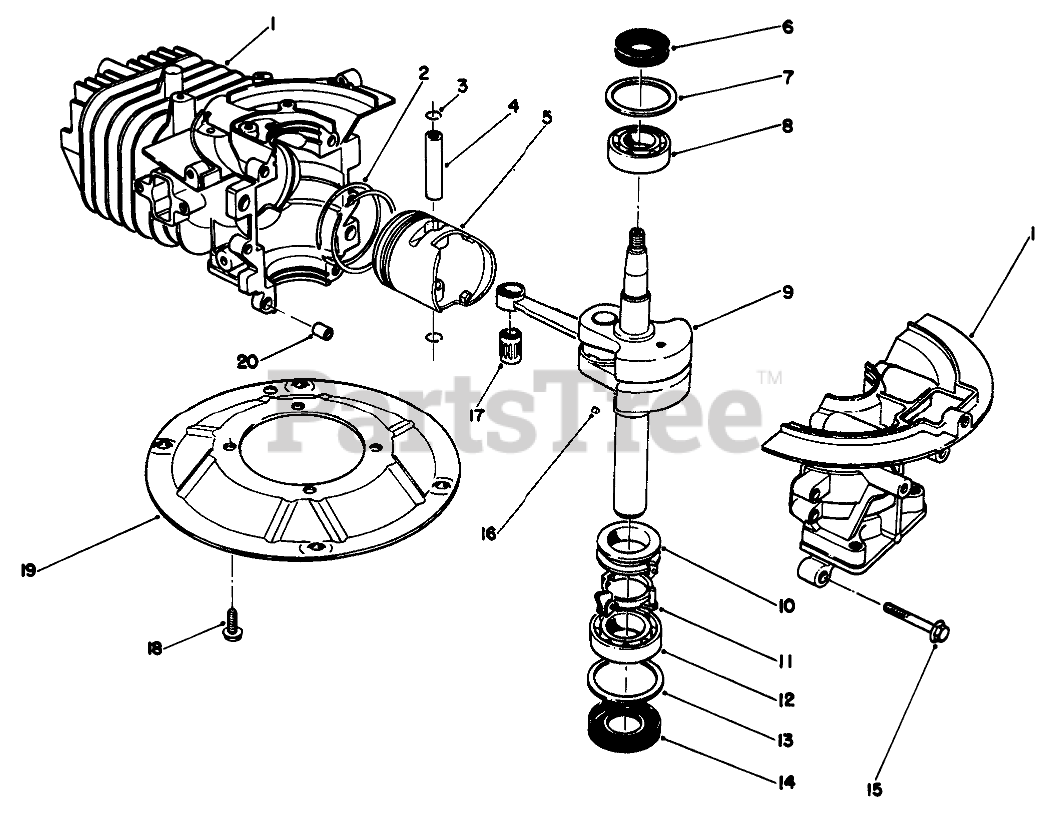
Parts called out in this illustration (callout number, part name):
1	CRANKCASE
2	RING SET
4	PIN-PISTON
5	PISTON
6	OIL SEAL
7	WASHER-UPPER
8	BEARING-UPPER
9	CRANKSHAFT
10	SPACER
11	BRACKET
12	LOWER BRG
13	WASHER-LOWER
14	SEAL-OIL
17	BEARING
19	PLATE-MOUNTING
